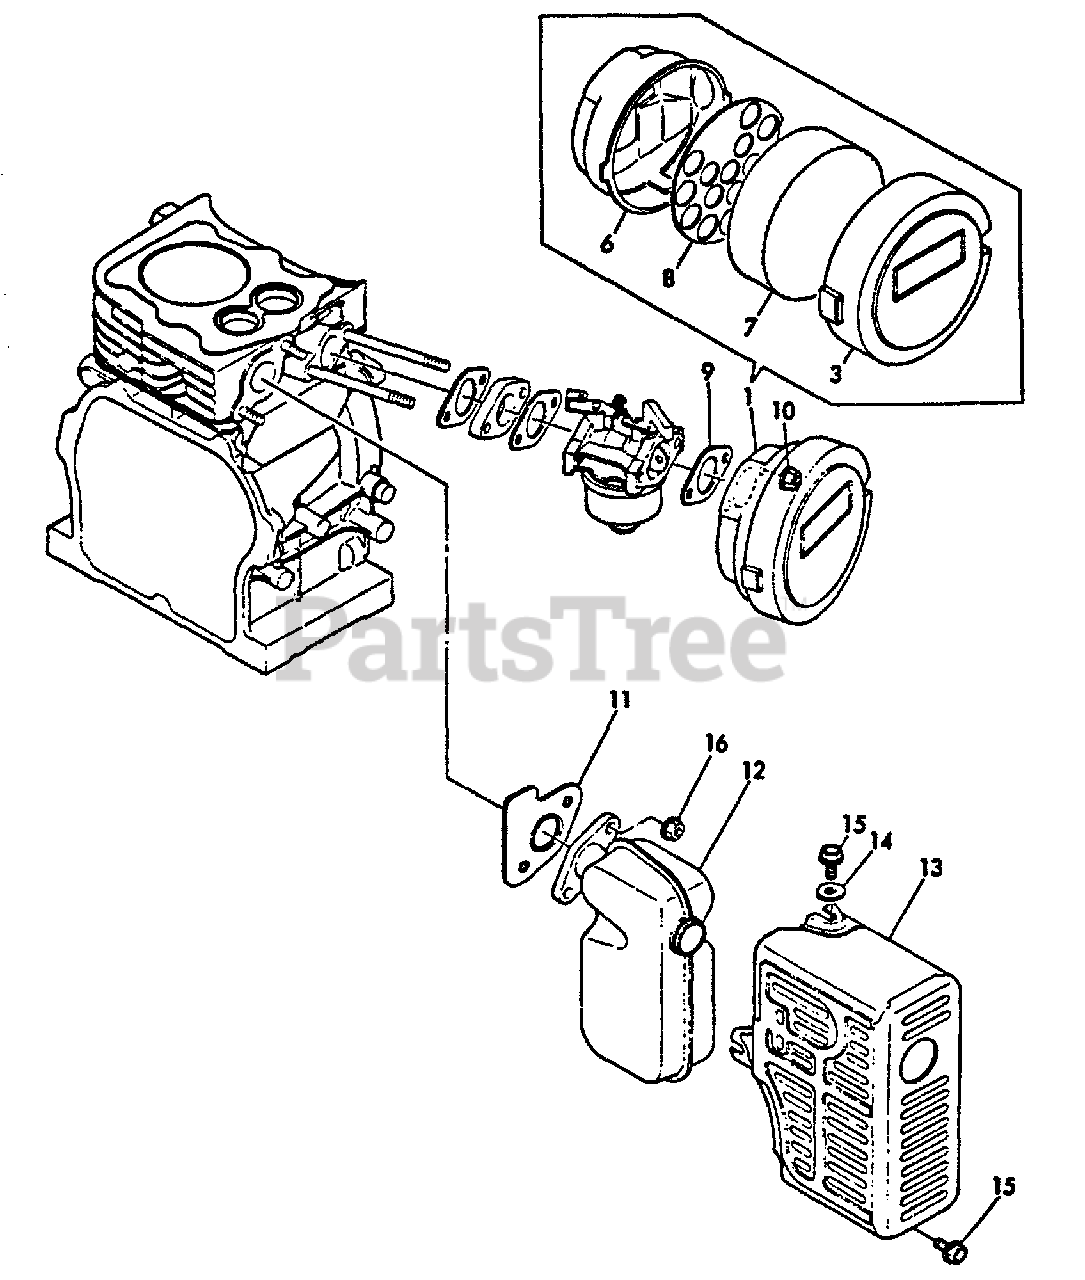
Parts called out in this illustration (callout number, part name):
1	AIR CLEANER ASSY
3	AIR FILTER COVER ASSY
6	CASE, AIR FILTER
7	FILTER, AIR
8	RETAINER, AIR FILTER
9	GASKET, INTAKE
10	NUT - 6 -- FLANGE
11	GASKET, EXHAUST
12	MUFFLER
13	COVER, MUFFLER
14	WASHER
15	BOLT - 6X8 -- PLATED
16	NUT - 6 -- FLANGE
